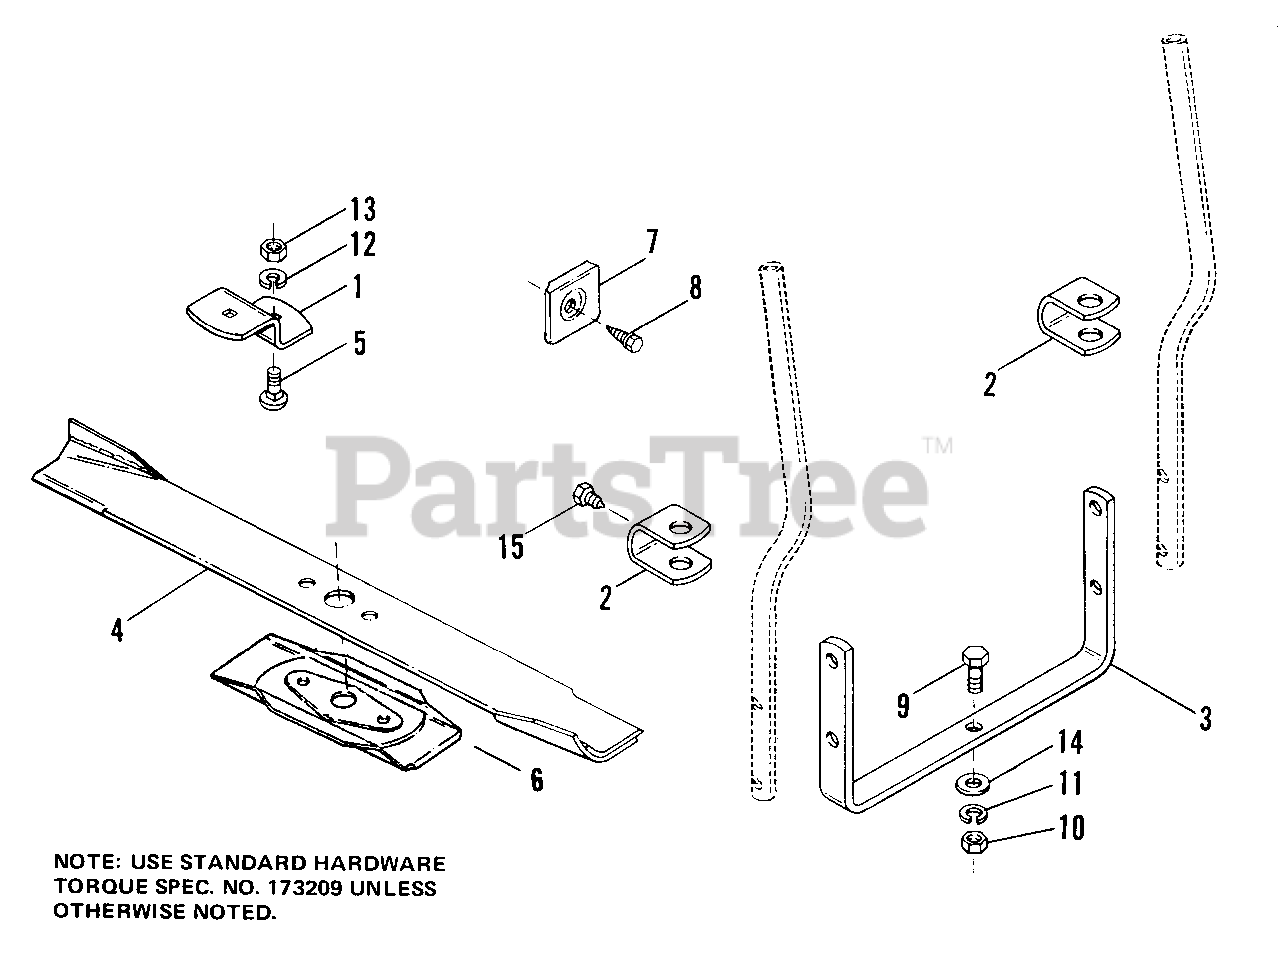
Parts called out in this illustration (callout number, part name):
1	SUPPORT, Adaptor
3	SUPPORT, Bracket
4	BLADE ASSY
5	BOLT, Carriage, 5/16-18 x 5/8
6	STIFFNER, Blade
7	DEFLECTOR, Muffler
9	CAPSCREW, Hex Hd., 3/8-16 x 1
10	NUT, Hex, 3/8-16
11	LOCKWASHER, Spring, 3/8
12	LOCKWASHER, Spring, 5/16
13	NUT, Hex, 5/16-18
14	WASHER, Plain, 3/8
15	SCREW, Thd. Cutting, Hex Hd., 1/4-20 x 3/8
